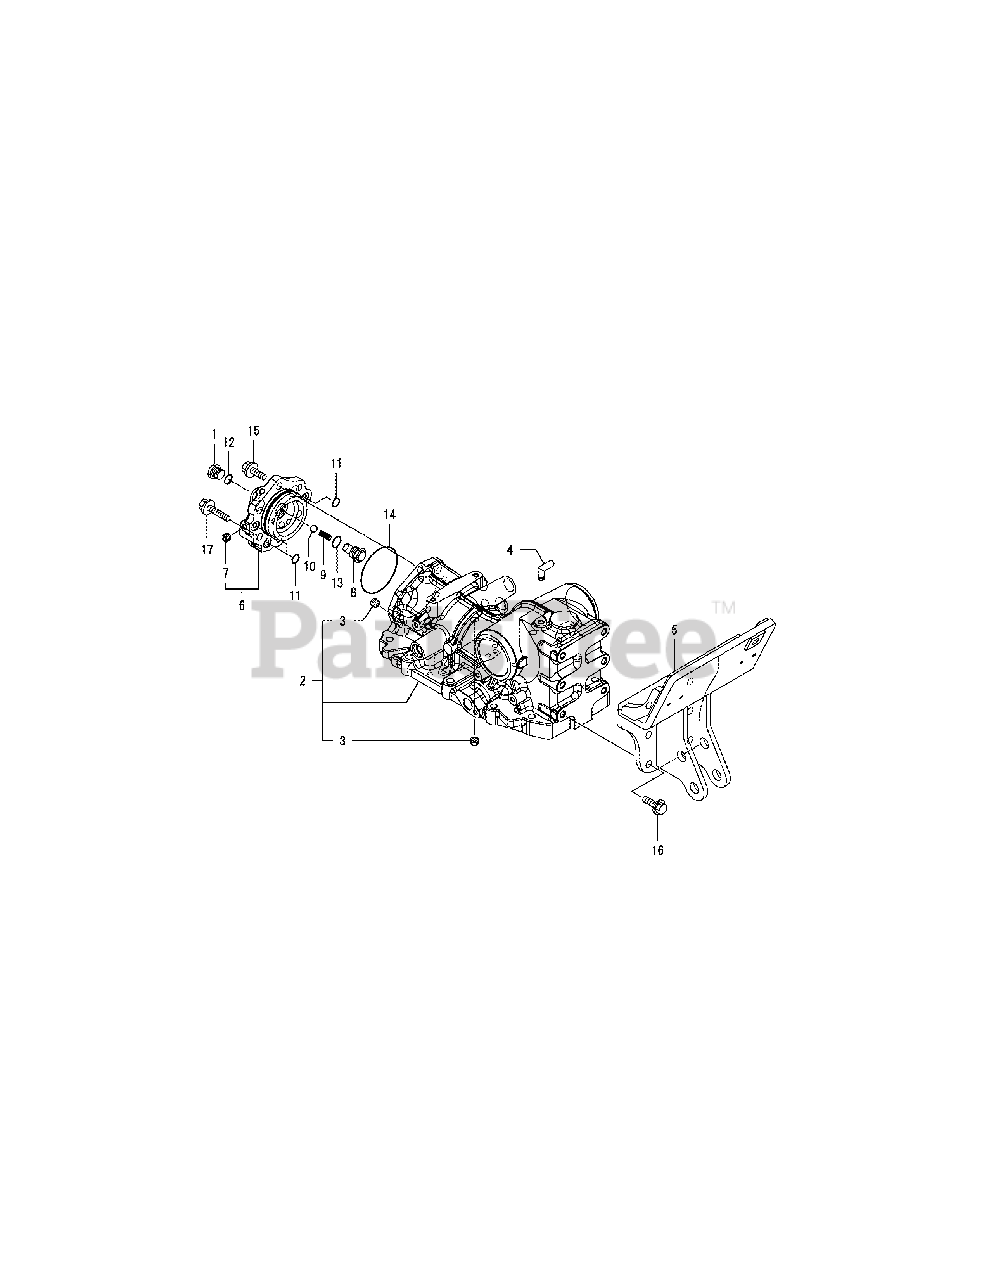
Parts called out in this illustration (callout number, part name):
3	PLUG PT1/8, SCREW
4	PIPE, BREATHER
5	HINGE, P TOP LINK
6	HEAD ASSY, CYLINDER
7	PLUG PT1/8, SCREW
8	PLUG, CHECK VALVE
11	O-RING 1B P-14.0
12	O-RING 1B P-14.0
13	O-RING 1B P-18.0
14	O-RING, 1B G 80.0
15	BOLT M12X 30 PLATED
16	BOLT M12X 30 PLATED
